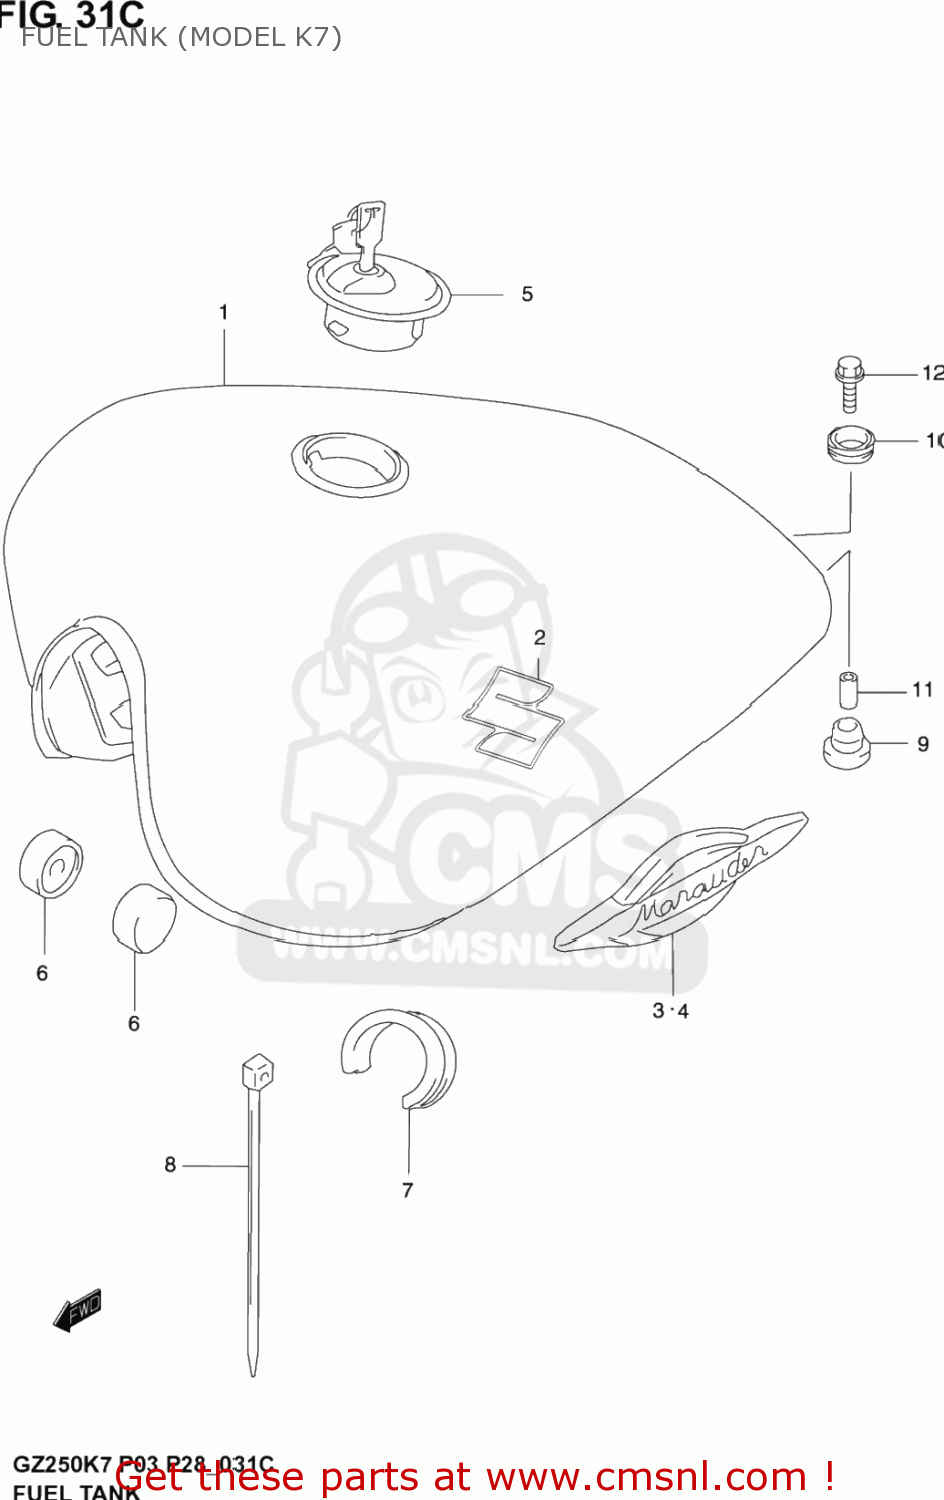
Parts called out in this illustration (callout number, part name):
1	TANK ASSY,FUEL(BLUE)
2	EMBLEM,S
3	EMBLEM,TANK
4	EMBLEM. FUEL TANK LH
5	CAP SET,FUEL TANK
6	CUSHION
7	CUSHION,FUEL TANK SIDE
8	CLAMP
9	CUSHION
10	CUSHION,FUEL TANK RR
11	SPACER(6.5X9X18)
12	BOLT
